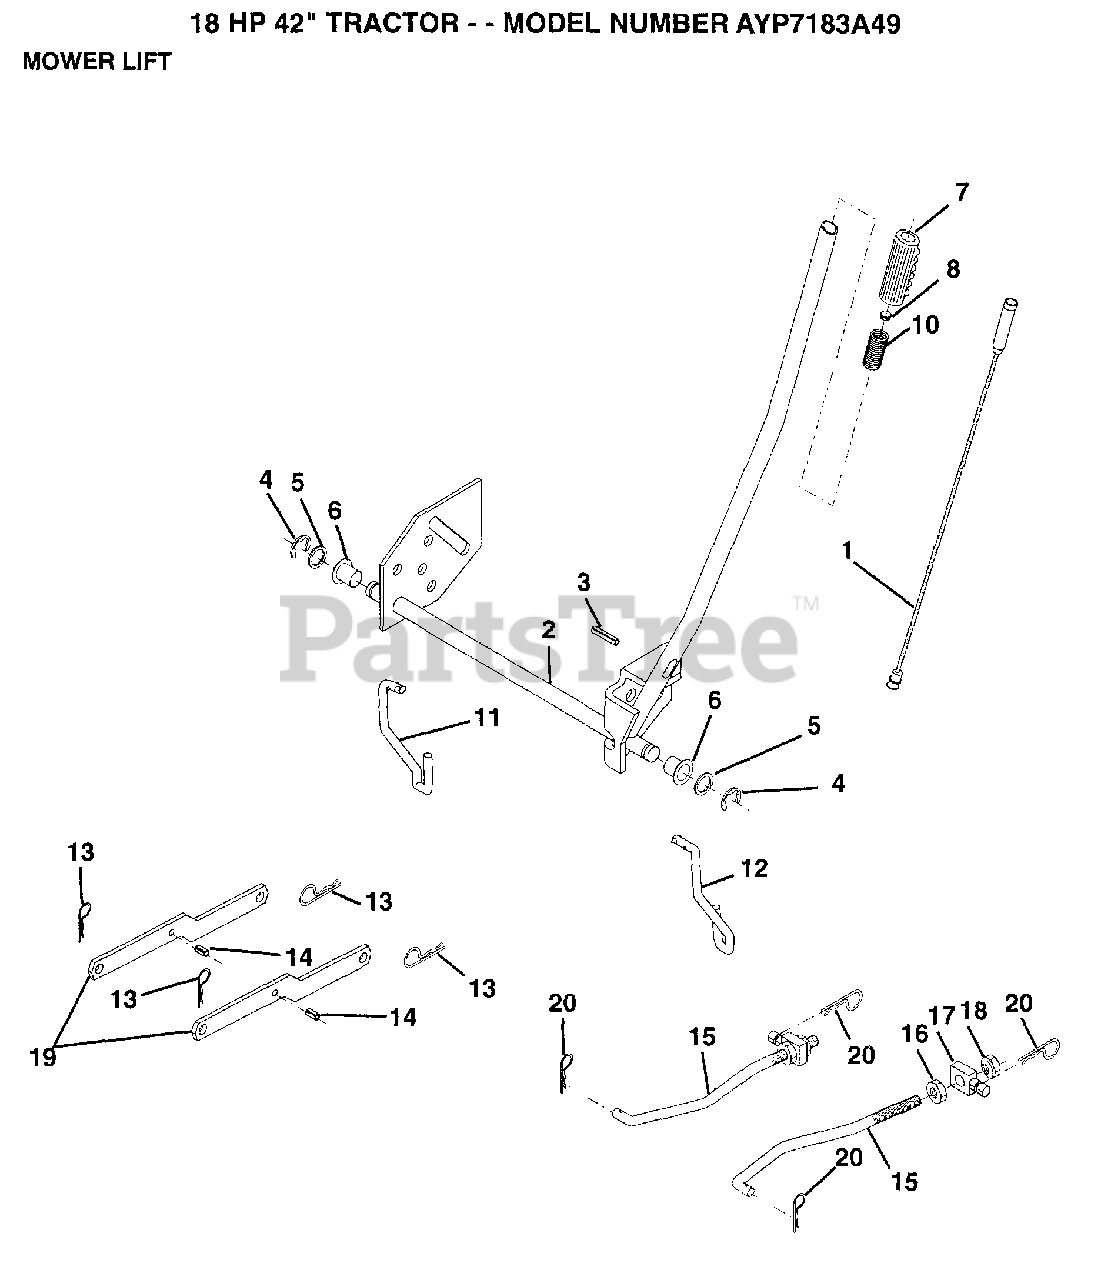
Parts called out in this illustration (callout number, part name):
1	WIRE ASM
3	PIN-GROOVE LT
5	WASHER
6	NYLON BEARING
7	GRIP
11	LINK LIFT LH
12	LIFT LINK RH
14	"PIN,SPRING"
15	LINK.FRONT
16	NUT
17	TRUNION
18	NUT.LK.W/WSH.1/2.
20	RETAINER.SPRING
